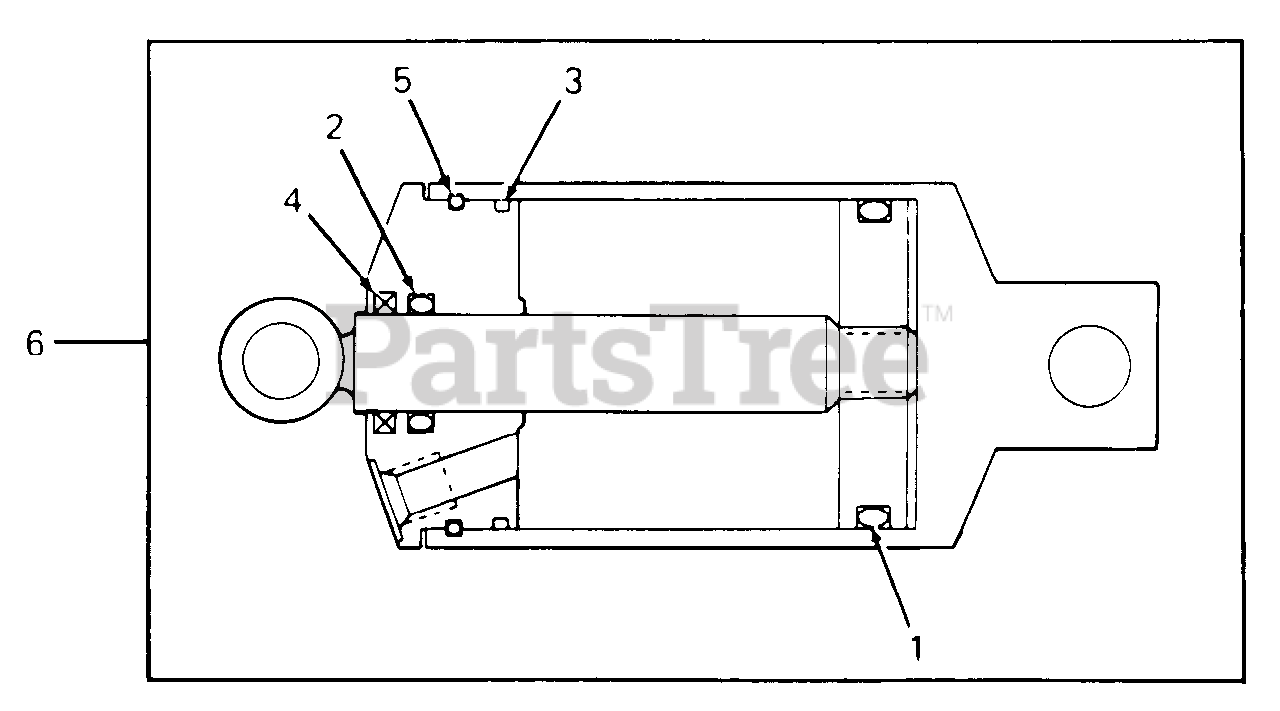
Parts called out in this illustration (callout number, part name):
4	Seal, Hydraulic Cylinder Piston Rod Wiper
5	Retainer, Hydraulic Cylinder
6	Cylinder, Hydraulic
